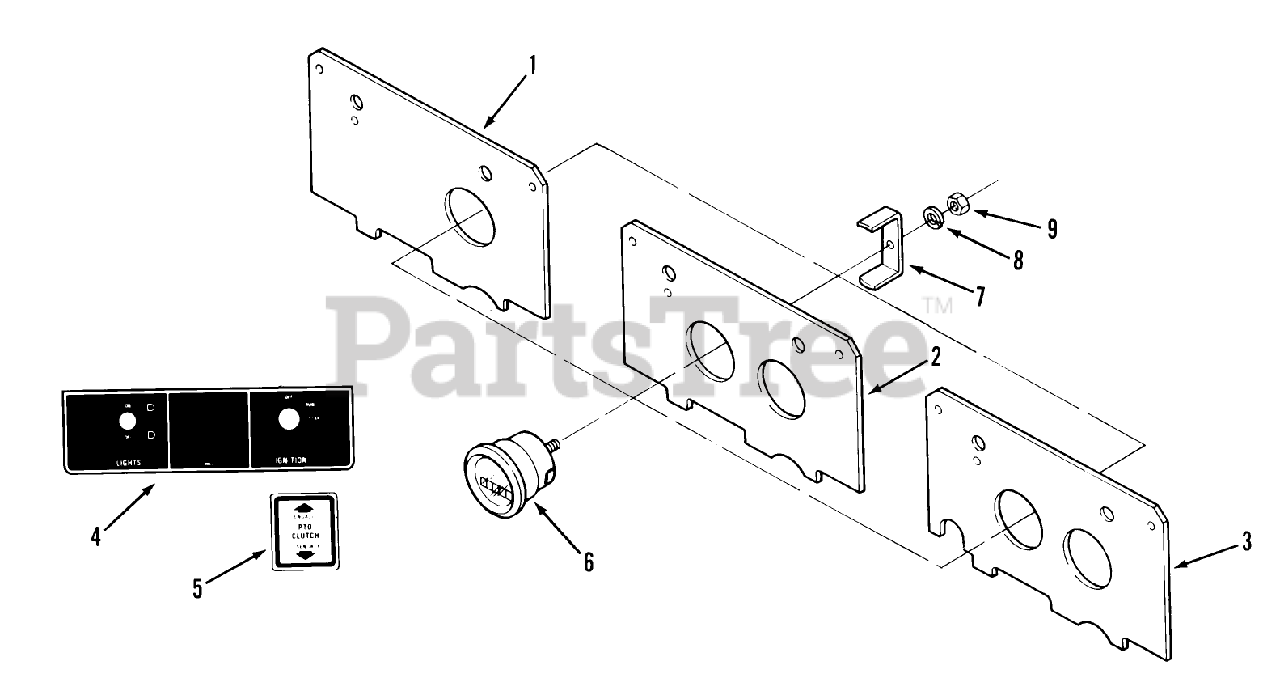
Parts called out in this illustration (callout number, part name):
1	Hoodstand Plate
2	PLATE HOODSTAND B
3	Plate-Hood Stand
4	DECAL-BACK PLATE-SWI
5	DECAL-PTO CLUTCH
6	Hour Meter
7	HOUR METER CLAMP
8	Lockwasher
9	Hex Nut
